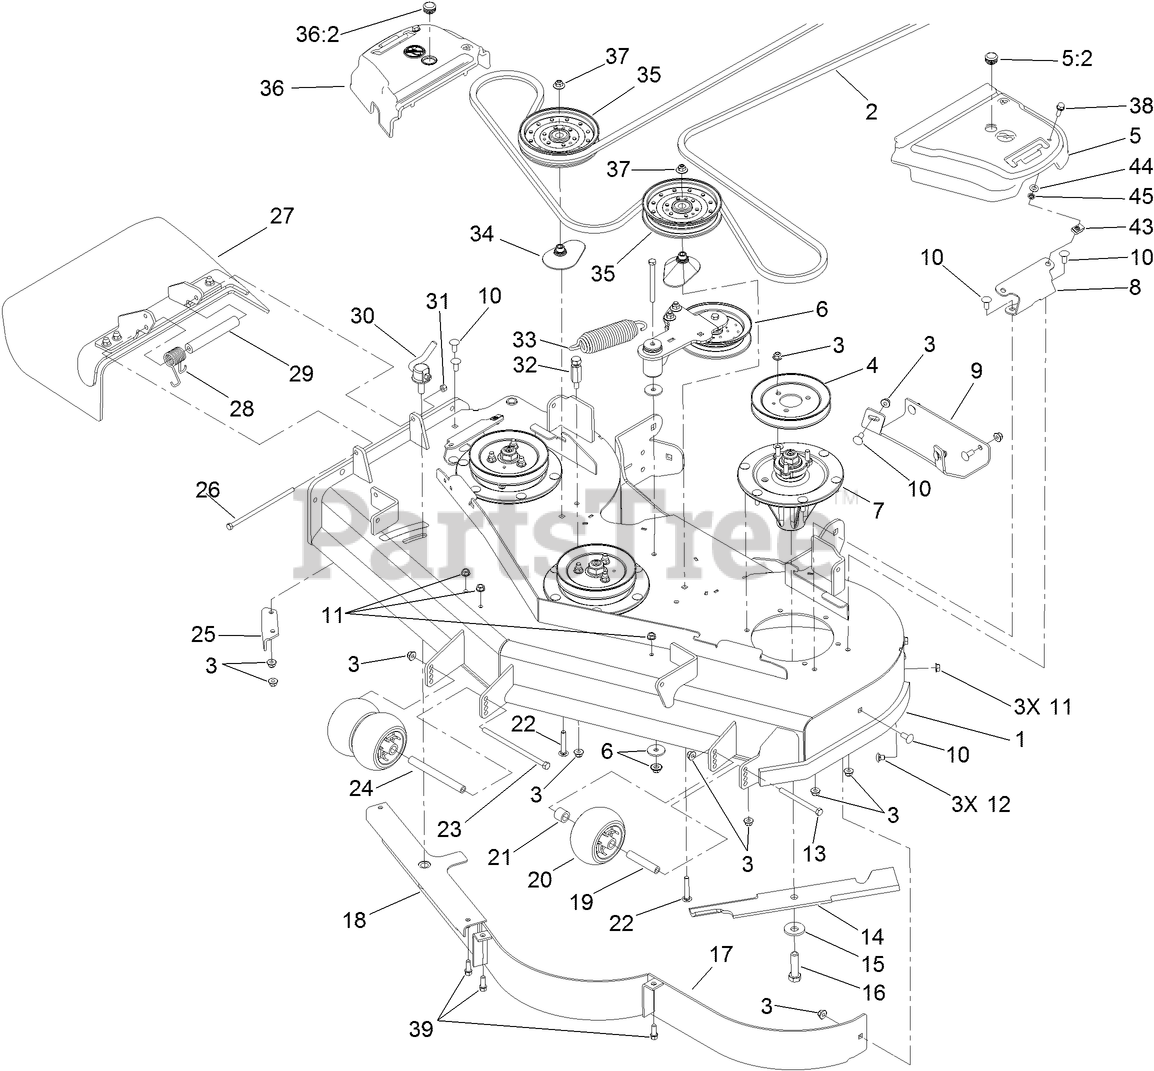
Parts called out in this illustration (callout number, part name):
1	DECK DECAL ASM
2	BELT-V
3	NUT-HF, NI
4	PULLEY
5	LH BELT COVER ASM
5:2	PLUG-PLASTIC
6	IDLER ARM ASM
7	SPINDLE ASM
8	BRACKET-COVER, BELT
9	PLATE-SKID
10	SCREW-CARR
11	NUT-HHF, WHIZ
12	SCREW-CARR
13	SCREW-HH
14	BLADE-18IN, HI FLOW
15	Washer-Blade Bolt, Heavy
16	SCREW-BLADE
17	BAFFLE ASM
18	BAFFLE
19	TUBE-SPANNER
20	ROLLER-SCALP, ANTI
21	TUBE-SPACER
22	BOLT-CARR, SHORT NECK
23	SCREW-HH
24	SPACER-WHEEL
25	BAFFLE-DISCHARGE
26	SCREW-HH
27	RUBBER DEFLECTOR ASM
28	SPRING-TORSION
29	SPACER
30	LEVER ASM
31	NUT-LOCK, NI
32	ANCHOR-SPRING, TALL
33	SPRING-EXTENSION
34	SPACER-PULLEY
35	PULLEY-IDLER, FLAT
36	RH BELT COVER ASM
36:2	PLUG-PLASTIC
37	NUT-FLANGE, NI
38	SCREW-HHF
39	SCREW-HWH
43	NUT-U
44	WASHER-THRUST
45	NUT-PUSH
